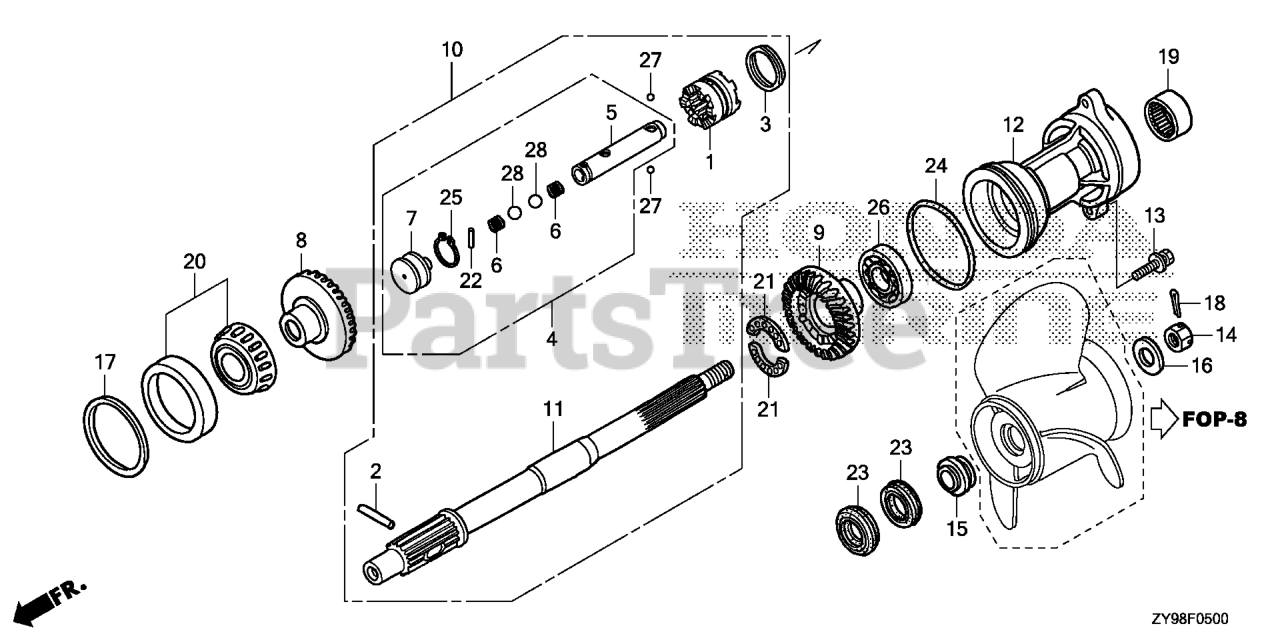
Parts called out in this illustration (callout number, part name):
1	SHIFTER, CLUTCH
2	PIN, SHIFTER (8X47)
3	RING, CROSS PIN
4	SLIDER, SHIFT
5	SLIDER, SHIFT
6	SPRING, SHIFT
7	PLATE, SHIFT
8	GEAR, FR. BEVEL
9	GEAR, RR. BEVEL
10	SHAFT ASSY., PROPELLER
11	SHAFT, PROPELLER
12	HOLDER, PROPELLER SHAFT *NHB14M* (AQUA MARINE SILVER METALLIC)
13	BOLT-WASHER (10X40)
14	NUT, CASTLE (18MM)
15	WASHER, PROPELLER THRUST
16	WASHER, PLAIN (18.5MM)
17	SHIM A, BEVEL (0.10) (FR.)
17	SHIM B, BEVEL (0.15) (FR.)
17	SHIM C, BEVEL (0.30) (FR.)
17	SHIM D, BEVEL (0.50) (FR.)
18	PIN, SPLIT (4.0)
19	BEARING, NEEDLE (30X37X26)
19	BEARING (30X37X26)
20	BEARING, TAPERED ROLLER (50X82X21.5)
21	BEARING, BALL (28X38X3)
22	ROLLER (3X12.8)
23	SEAL, WATER (30X45X7)
24	O-RING (94X4.1)
25	CIRCLIP (OUTER) (14MM)
26	BEARING, RADIAL BALL (6208)
27	BALL, STEEL (#7) (7/32)
28	BALL, STEEL (#11) (11/32)
